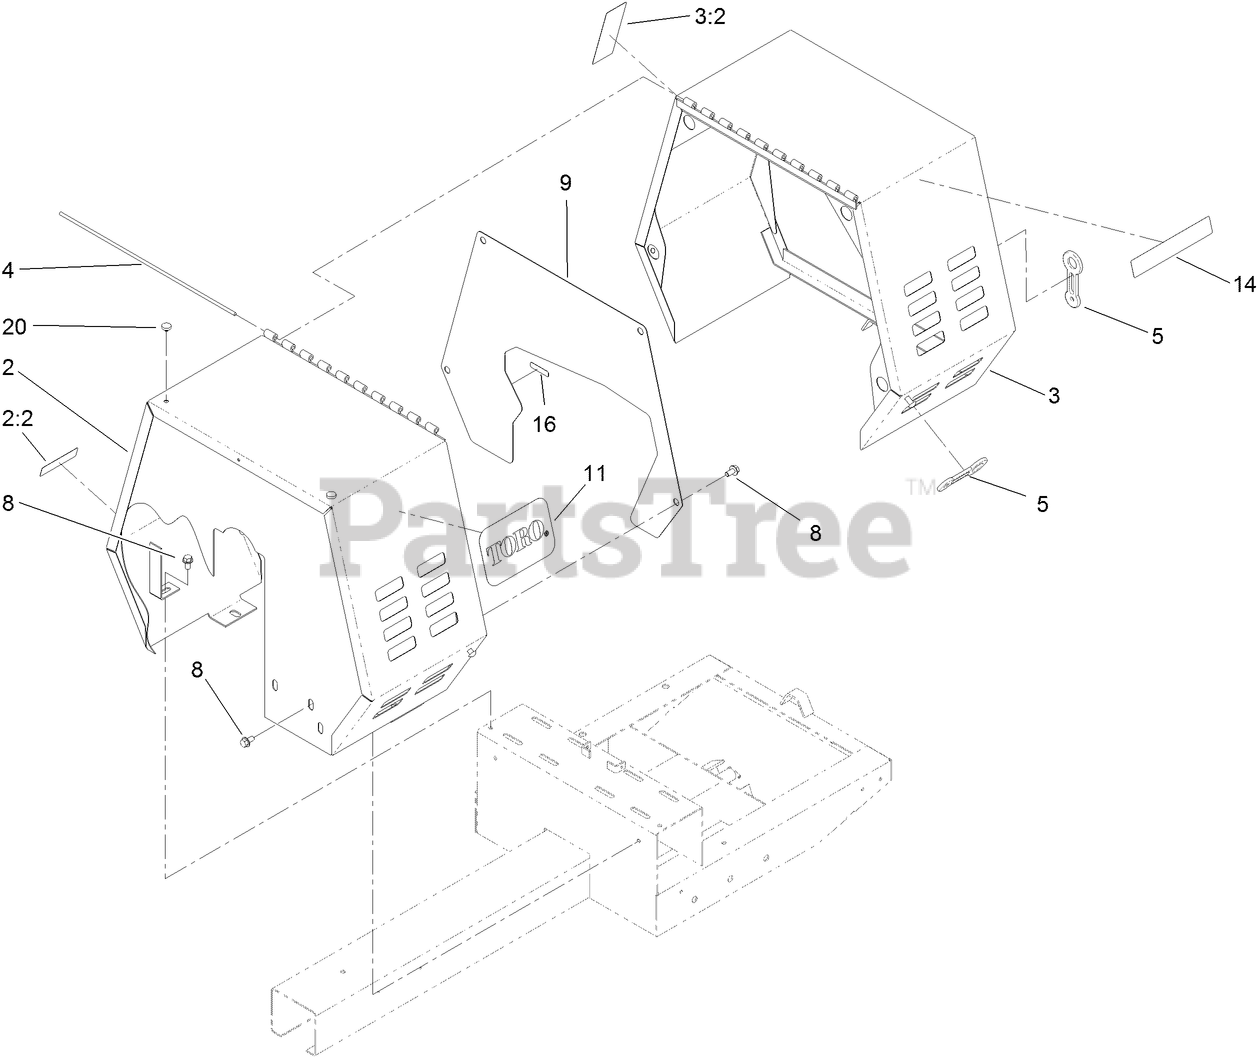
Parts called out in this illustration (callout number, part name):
2	STATIONARY COWL ASM
2:2	DECAL-ARRESTER, SPARK
3	MOVABLE COWL ASM
3:2	DECAL-WARNING
5	LATCH-RUBBER
8	SCREW-HWH
9	PLATE-ACCESS, BELT
11	DECAL
16	DECAL-GREASE
20	BUMPER
